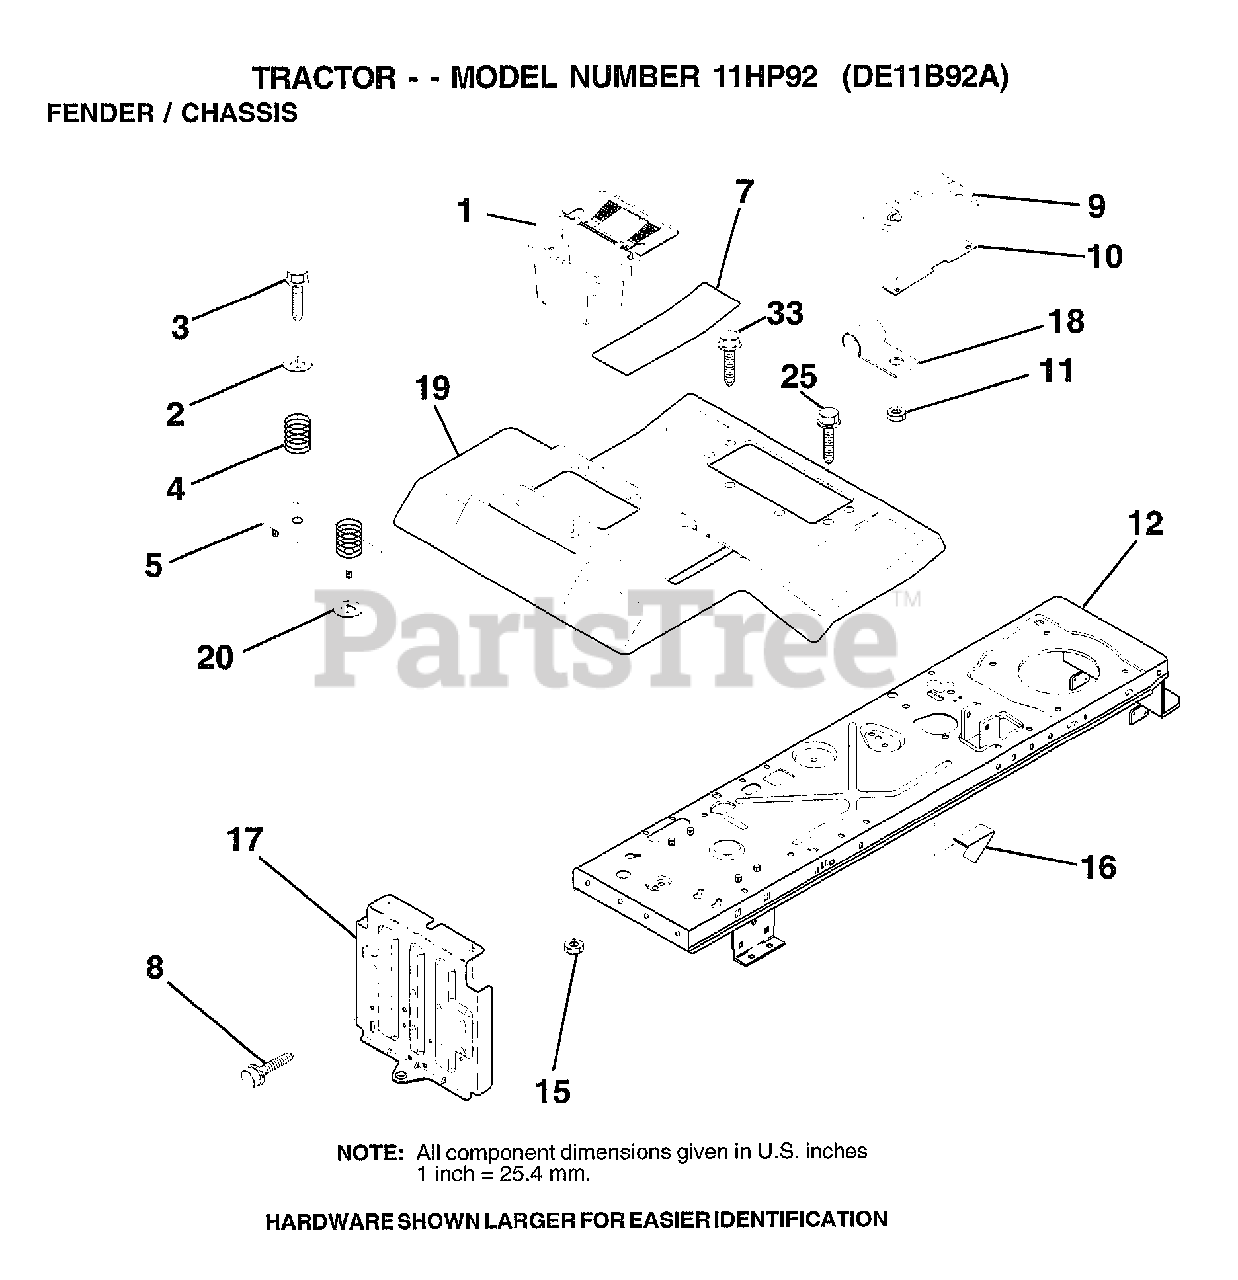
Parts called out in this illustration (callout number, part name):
1	"CASE,BATTERY.MECH"
2	WASHER
3	SCREW
4	SPRING COMPRESSIO
5	PLATE, BATTERY
7	PAD FOOTREST
8	SCREW
9	CONSOLE.SHIFT CONTROL
10	PLATE LOCK SHIFT
11	NUT
12	CHASSIS.WELD.ASM.
15	NUT HXKEP 1/4X20
17	DRAWBAR ASM LR
18	"CLIP,INSULATOR"
19	FENDER.FOOTREST
25	SCREW TAPPING
33	SCREW
